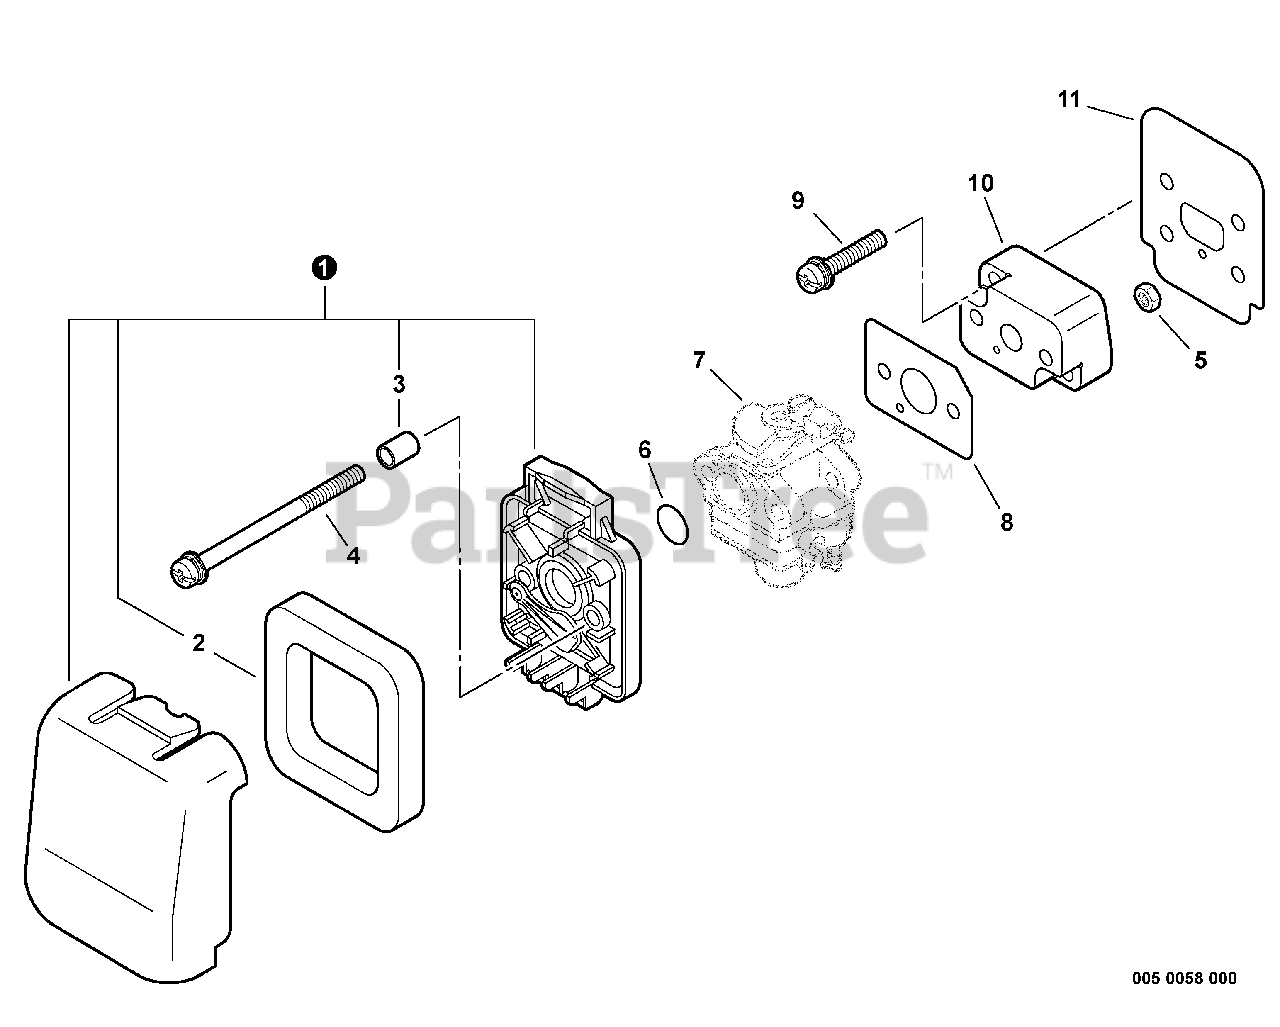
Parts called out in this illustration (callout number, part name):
1	AIR FILTER COVER KIT
2	FILTER, AIR
3	SLEEVE
4	SCREW - 5X64
6	O-RING - 15
7	CARBURETOR
8	GASKET, INTAKE
9	SCREW - 5X22
10	INSULATOR, INTAKE
11	SHIELD, INTAKE
